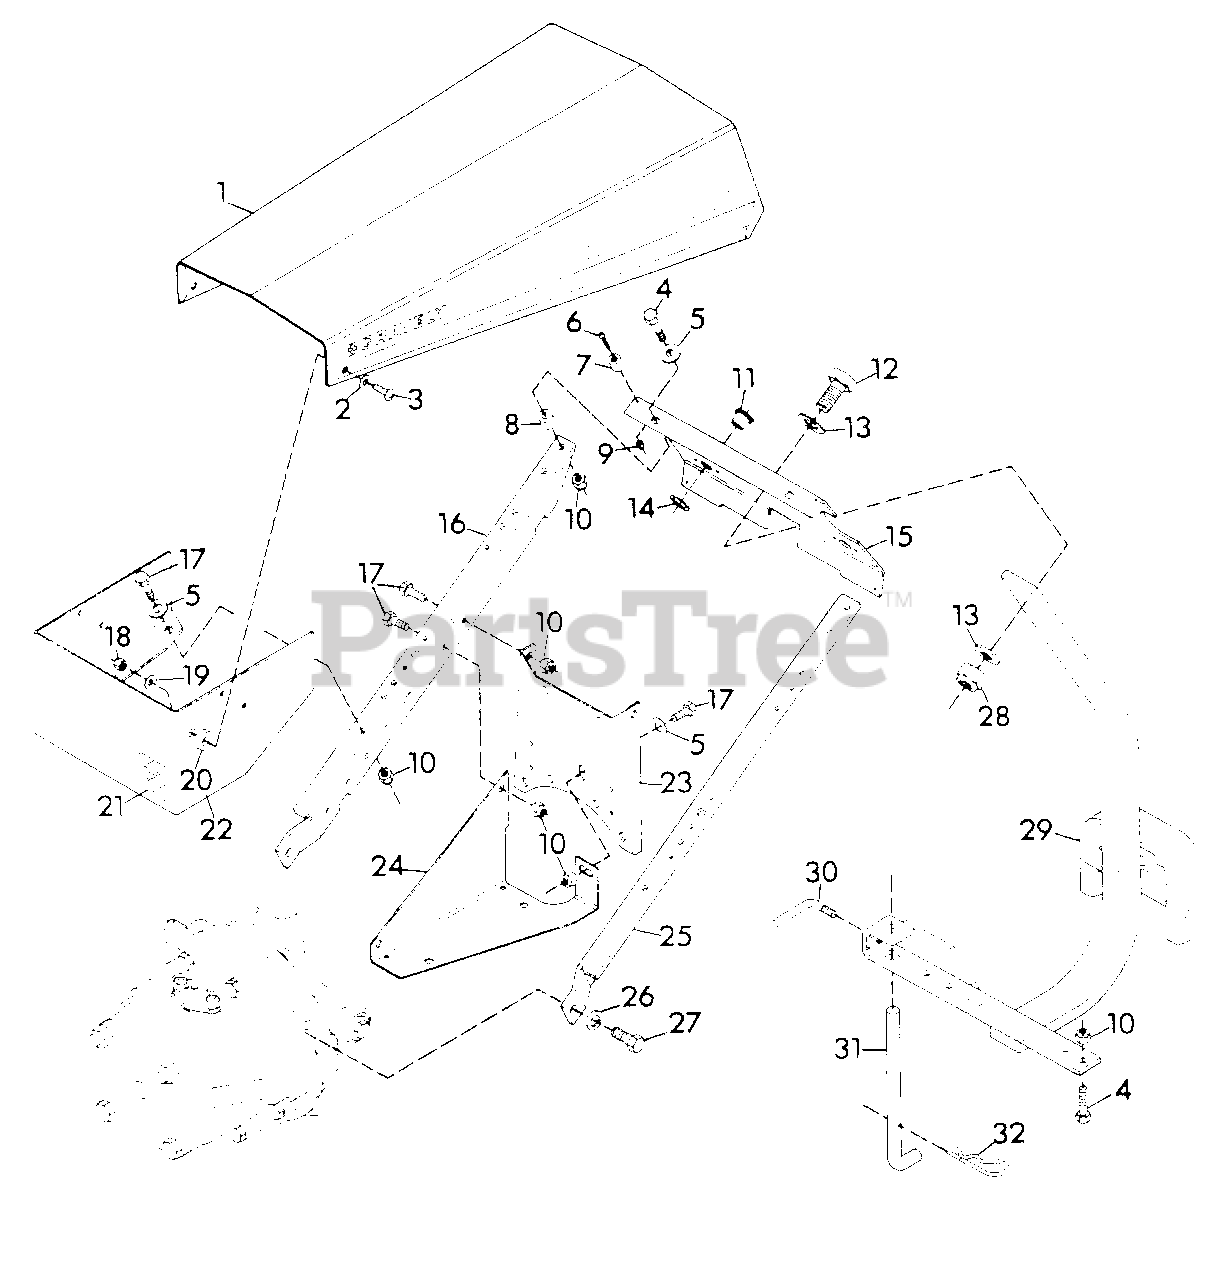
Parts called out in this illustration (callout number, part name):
1	ASSEMBLY, HOOD
2	WASHER, FLAT .281X.625X.065
3	SCREW, MACH. 1/4-20X1.00 PHD
4	BOLT, HEX 3/8-16X1.50
5	WASHER, FLAT .406X.812X.065
6	SCREW, MACH. 6-32X.625 PHD
7	BUMPER
8	BUSHING, REVERSE IDLER
9	NUT, MACH. LOCK 6-32
10	NUT, LOCK 3/8-16
11	BUSHING, .513X.750X.625
12	BOLT, HEX 5/8-11X2.00
13	WASHER, FLAT .656X1.250X.100
14	RING, RETAINING
15	PLATE, SILK SCREEN
16	SUPPORT, HANDLEBAR R.H.
17	BOLT, HEX 3/8-16X.875
18	NUT, LOCK 1/4-20
19	WASHER, FLAT .313X.875X.065
20	BUSHING, HOOD
21	DECAL
22	SUPPORT, HOOD
23	BRACKET
24	TRAY, BATTERY
25	SUPPORT, HANDLEBAR L.H.
26	WASHER, LOCK 1/2 REG.
27	BOLT, HEX 1/2-13X1.00
28	NUT, LOCK 5/8-11
29	WELDMENT, HITCH 8 H.P.
30	HANDLE, ADJUSTING
31	STAND, KICK
32	PIN, HAIR
NS	DECAL, 8
NS	DECAL, SIDE STRIPE
NS	DECAL, GRAVELY
NS	DECAL, 6 LEAD
NS	DECAL, 8 LEAD
NS	DECAL, PROFESSIONAL
